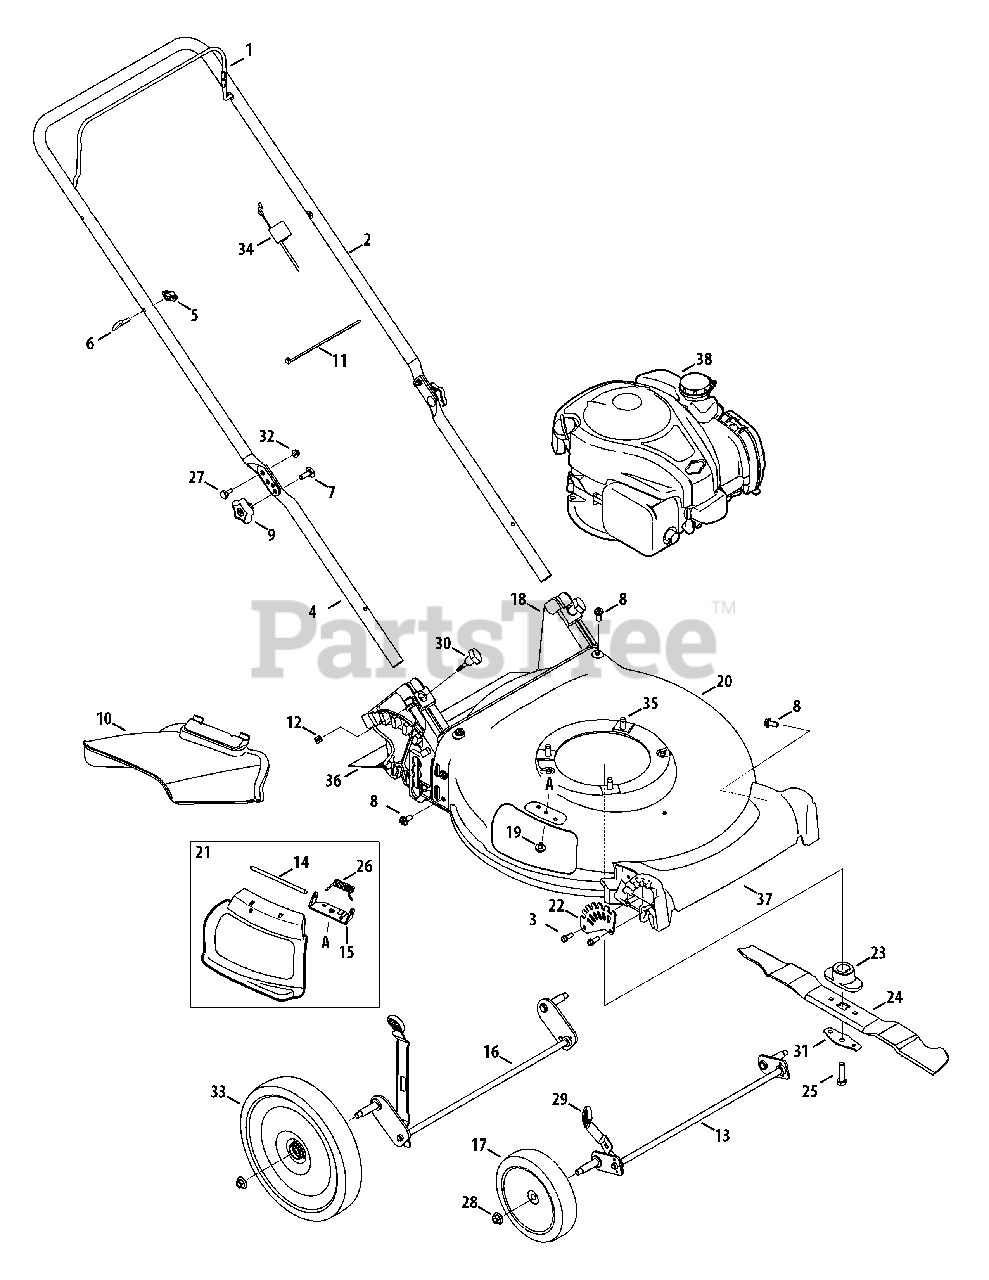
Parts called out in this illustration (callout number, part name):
1	Blade Control
2	Upper Handle
3	Screw, 1/4-15 x .750
4	Lower Handle
5	Wing Nut
6	Rope Guide
7	Carriage Screw, 5/16-18
8	Screw, 5/16-14 x .750
9	Hand Knob
10	Side Chute
11	Cable Tie
12	Nut, Sq., 1/4-20
13	Front Axle Assembly
14	Hinge Pin
15	Chute Deflector Bracket
16	Rear Axle Assembly
17	Wheel, 7 x 1.8
18	Rear Baffle
19	Screw, 1/4-20 x .500
20	Deck - 21"
21	Hinged Mulch Plug Assembly
22	Front Height Adjuster Plate
23	Blade Adapter
24	Mulching Blade
25	Screw , 3/8-24 x 1.50
26	Torsion Spring
27	Sldr. Screw, .375 x .126 x 1/4-20
28	Flange Lock Nut, 3/8-16
29	Adjustment Lever Knob
30	Wing Nut
31	Blade Bell Support
32	Nut, Flange Lock, 1/4-20
33	Wheel, 8 x 1.8
34	Control Cable
35	TT Screw, 3/8-16 x 1.0
36	Trail shield
37	Front Cover
38	Engine - 09P702-0007-F1
